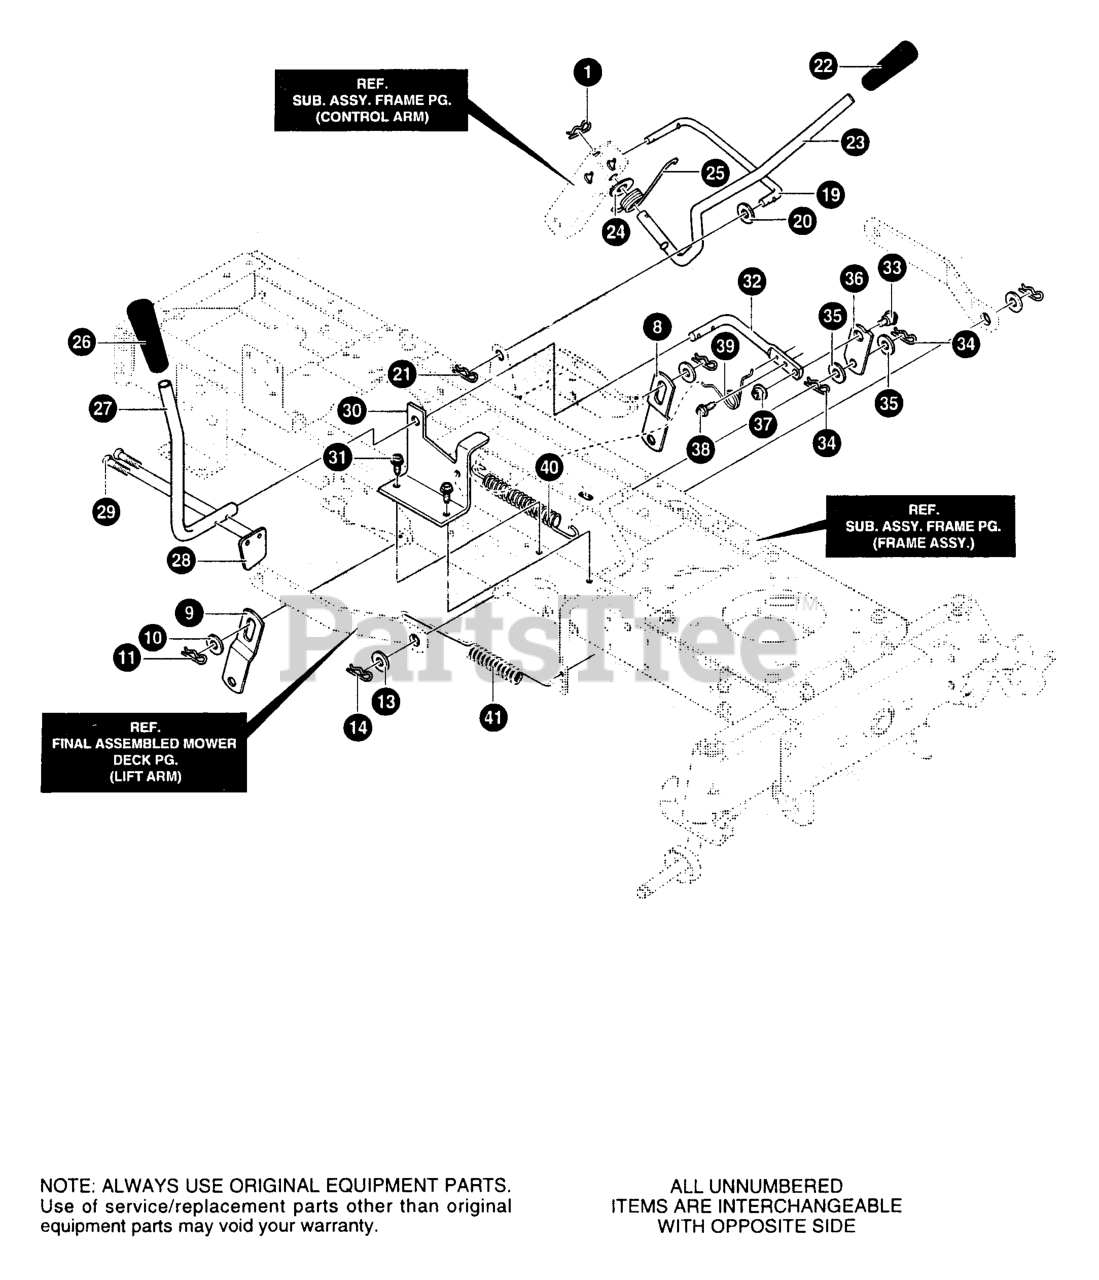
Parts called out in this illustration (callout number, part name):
1	HAIR PIN
8	LINK, LIFT LH
9	LINK-LIFT
10	FLATWASHER
11	PIN, HAIR
13	WASHER, FLAT
14	PIN, HAIR
19	LINK LIFT HANDLE
20	WASHER, FLAT
21	PIN, HAIR
22	GRIP, LIFT 1/2"
23	HANDLE, LIFT
24	WASHER, FLAT .550 x 1.00 x 11
25	TORSION SPRING,.657LG
26	Grip, PTO
27	HANDLE, PTO
28	PADDLE SWITCH
29	SCREW, THD FORM .246X1.050LG
30	BRACKET, PTO
31	SCREW, 5/16-18 x 0.50 HHWATAP
32	LEVER, PTO
33	BOLT, .50X.75 HHSH 3/8-16
34	PIN, HAIR.072 DIAX1.13LG
35	WASHER, FLAT .518 x .87 x 16
36	LINK PTO
37	NUT, 3/8-16 HWDFLLK MACK
38	SCREW, 5/16-18 x 0.75 HHWATAP
39	TORSION SPRING.33LG
40	SPRING, TENSION 1.010D 8.18LG
41	EXTENSION SPRING
